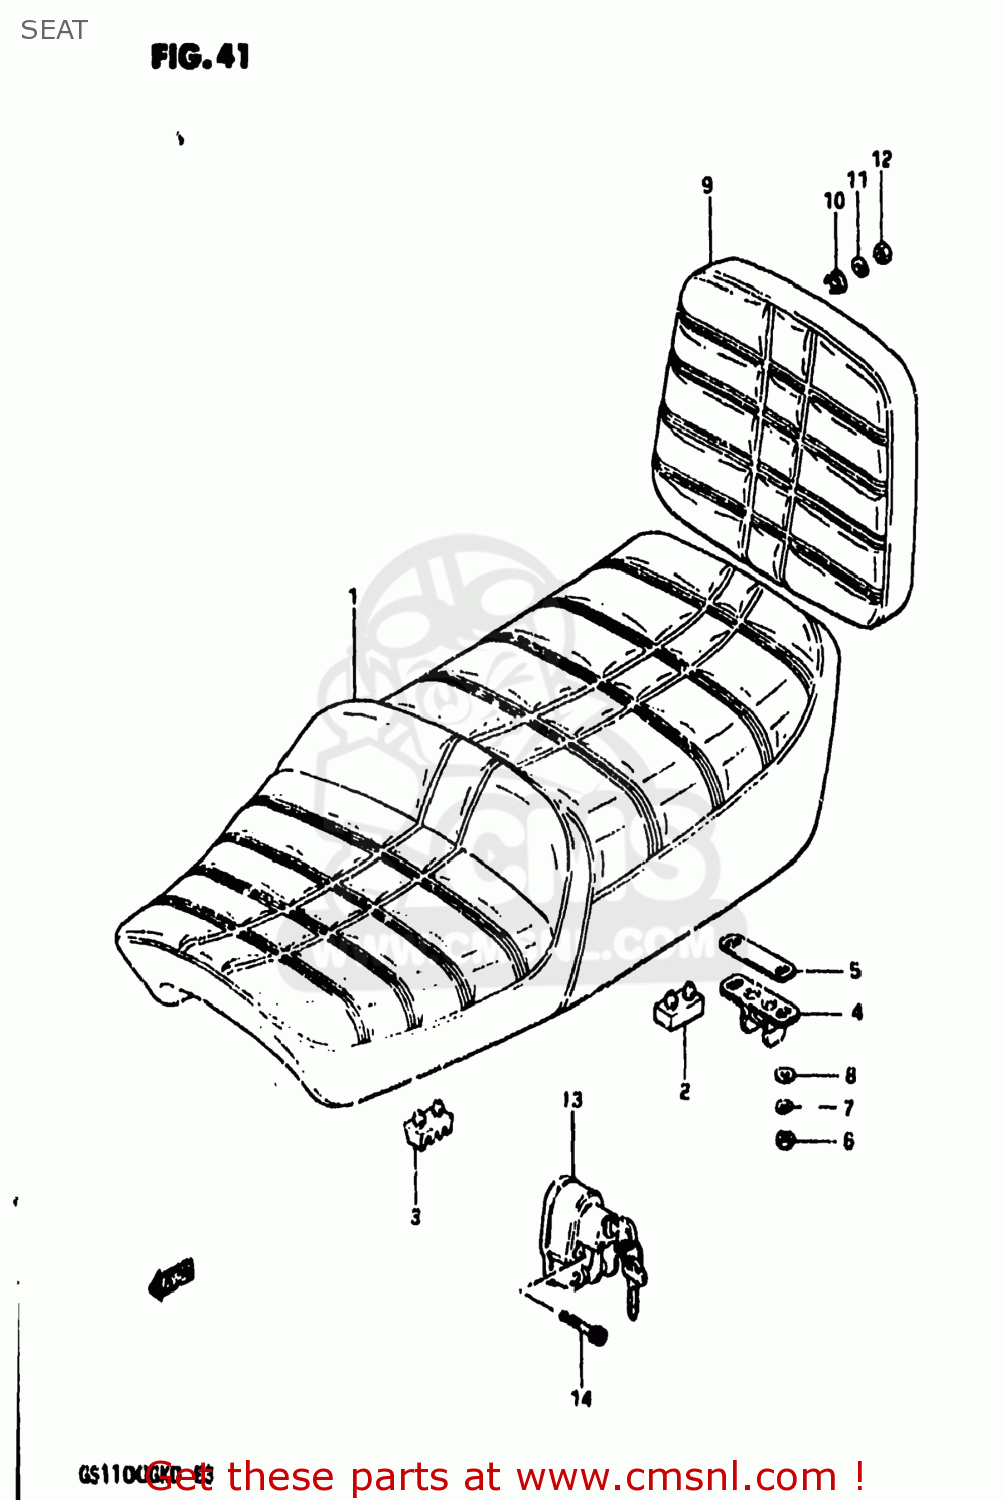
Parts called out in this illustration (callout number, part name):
1	SEAT ASSEMBLY
2	CUSHION(40X23X12.7)
3	CUSHION,SUPPORT(50X25X32)
4	STRIKER,SEAT LOCK
5	SHIM,SEAT LOCK STRIKER
6	NUT 6MM
7	LOCK WASHER
8	WASHER
9	PAD ASSEMBLY
10	WASHER
11	LOCK WASHER
12	NUT 6MM
13	LOCK ASSY,HELMET
14	BOLT 5X25
